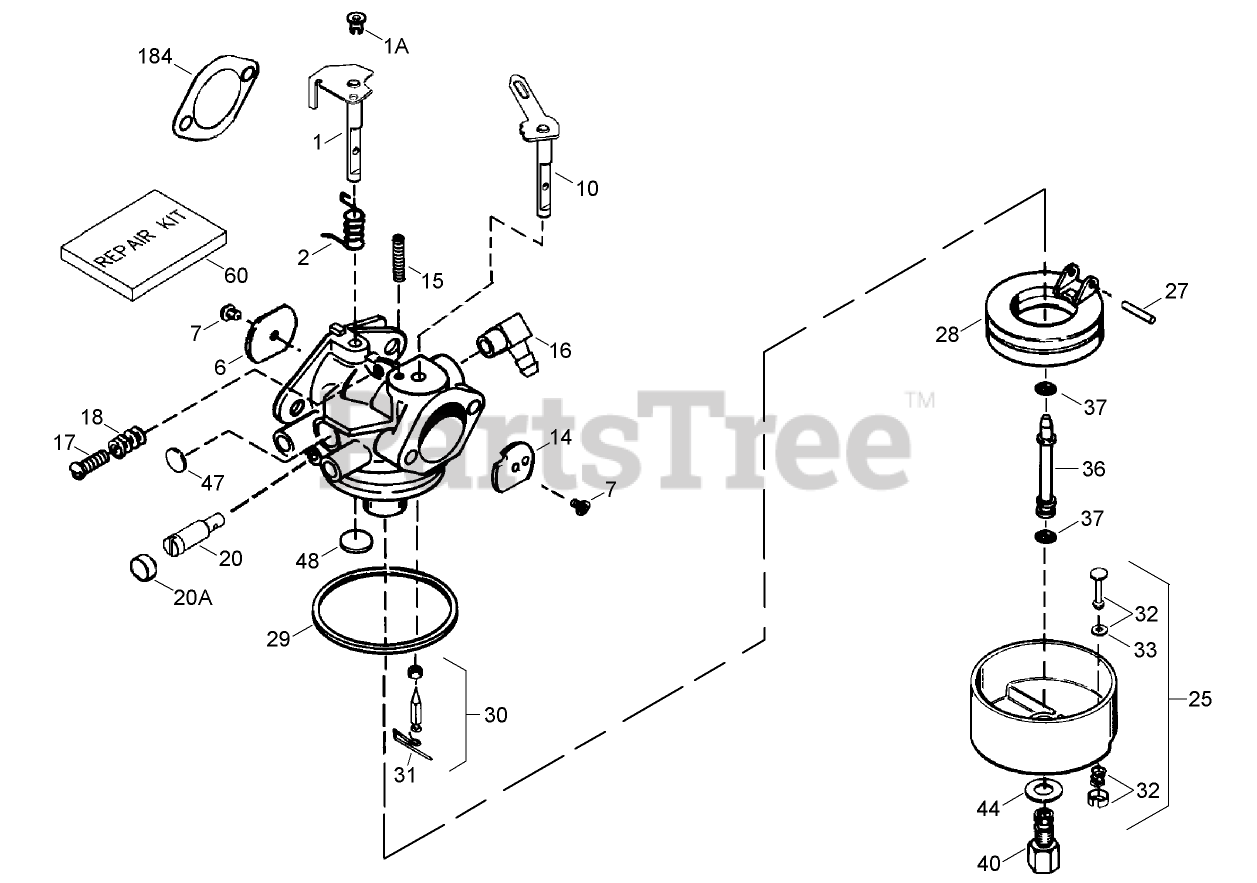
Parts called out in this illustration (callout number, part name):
1	Throttle Shaft and Lever ASM
1A	Bushing
2	Spring-Return, Throttle
6	Shutter-Throttle
7	Screw-Shutter
10	Choke Shaft and Lever ASM
14	Shutter-Choke
15	Spring-Positioning, Choke
16	Fitting-Fuel
17	Screw-Throttle Crack and Idle Speed
18	Spring-Tension
20	Screw-Restrictor, Idle
20A	Cap-Screw, Idle Restrictor
25	Float Bowl ASM (Incl. Ref. #32 and 33)
27	Shaft-Float
28	Float (Plastic)
29	O Ring-Bowl, Float
30	Inlet Needle, Seat Clip Assy. (Incl. No. 13)
31	Clip-Spring
32	Bowl Drain ASM
33	Gasket-Plunger, Drain
36	Tube-Nozzle, Main
37	O-Ring
40	Nut-Bowl, High Speed
44	Washer-Nut, Bowl
47	Plug-Welch, Idle Mixture Well
48	Plug-Welch, Atmospheric Vent
60	Repair Kit
184	Gasket-Carburetor To Intake Pipe
